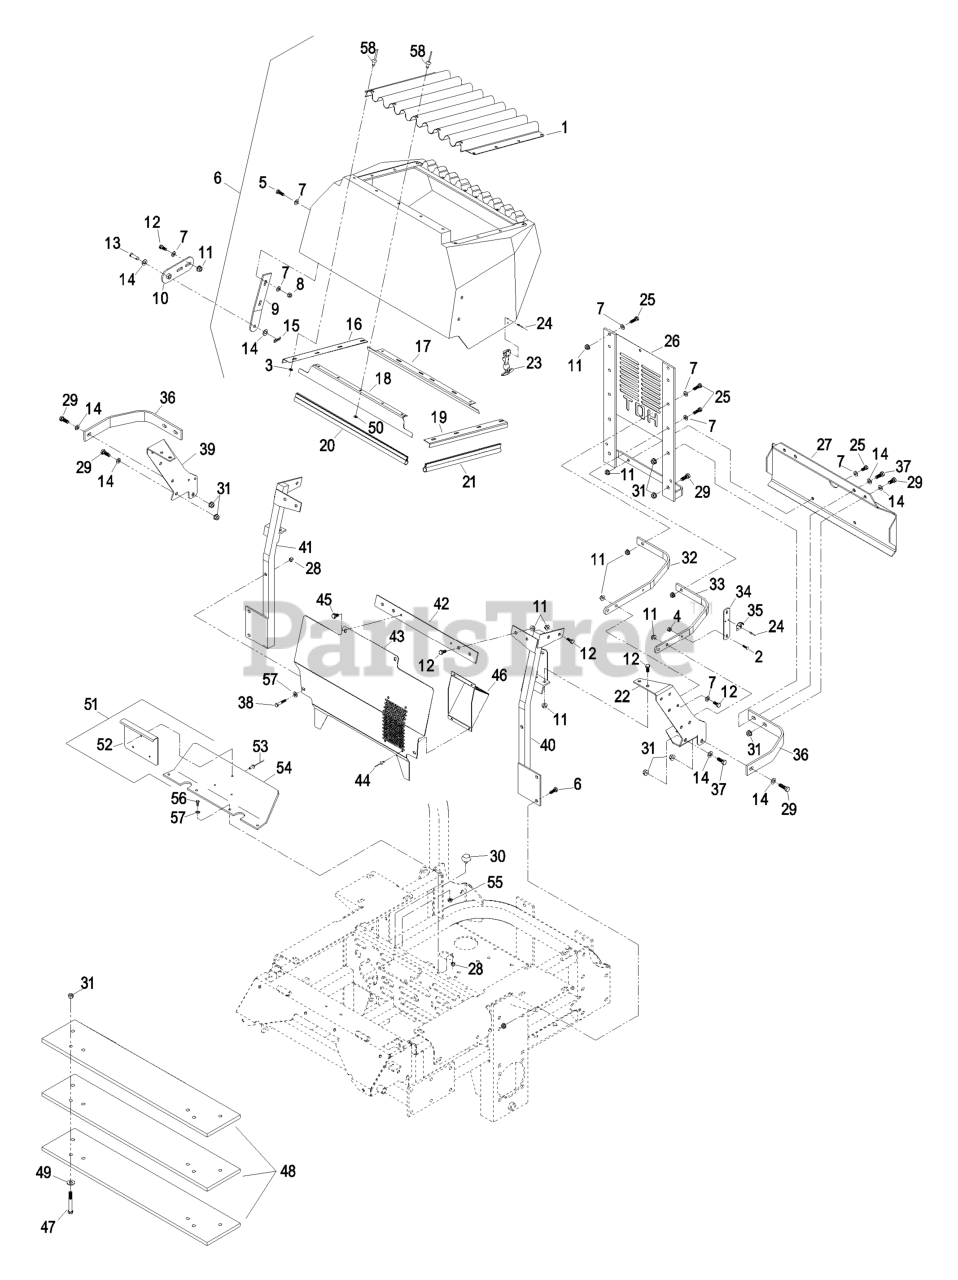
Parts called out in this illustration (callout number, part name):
1	SCREEN-RADIATOR
2	SCREW-HEAD, TRUSS
3	WASHER-FLAT
4	NUT-LOCK, NI
5	SCREW-HH
7	WASHER-PLAIN
8	NUT-LOCK, NI
9	PLATE-HINGE, HOOD
10	SHACKLE-HINGE
12	SCREW-HH
13	PIN-CLEVIS
14	WASHER-FLAT
15	PIN-COTTER
16	ANGLE-RADIATOR, RH
17	ANGLE-RADIATOR, BOTTOM
18	ANGLE-RADIATOR, TOP
19	ANGLE-RADIATOR, LH
20	SEAL-TRIM
21	SEAL-TRIM
22	PLATE-SIDE, LH
23	LATCH-RUBBER
25	SCREW-HH
28	NUT-LOCK, NI
29	SCREW-HH
31	NUT-HHF, WHIZ
34	BAR-HOOK, LATCH
36	STRAP-GUARD
37	SCREW-HH
38	SCREW-HH
39	PLATE-SIDE, RH
40	BRACE-RADIATOR, LH
43	DEFLECTOR-AIR
44	RIVET-POP
45	SCREW-HWHTF
46	PLENUM-INTAKE, AIR
47	SCREW-CARR
48	BAR,WEIGHT 38.1#
49	WASHER-BELLEVILLE
50	WASHER-SPRING
53	RIVET-POP
54	SHIELD-ENGINE
56	SCREW-HH
57	WASHER-FLAT
